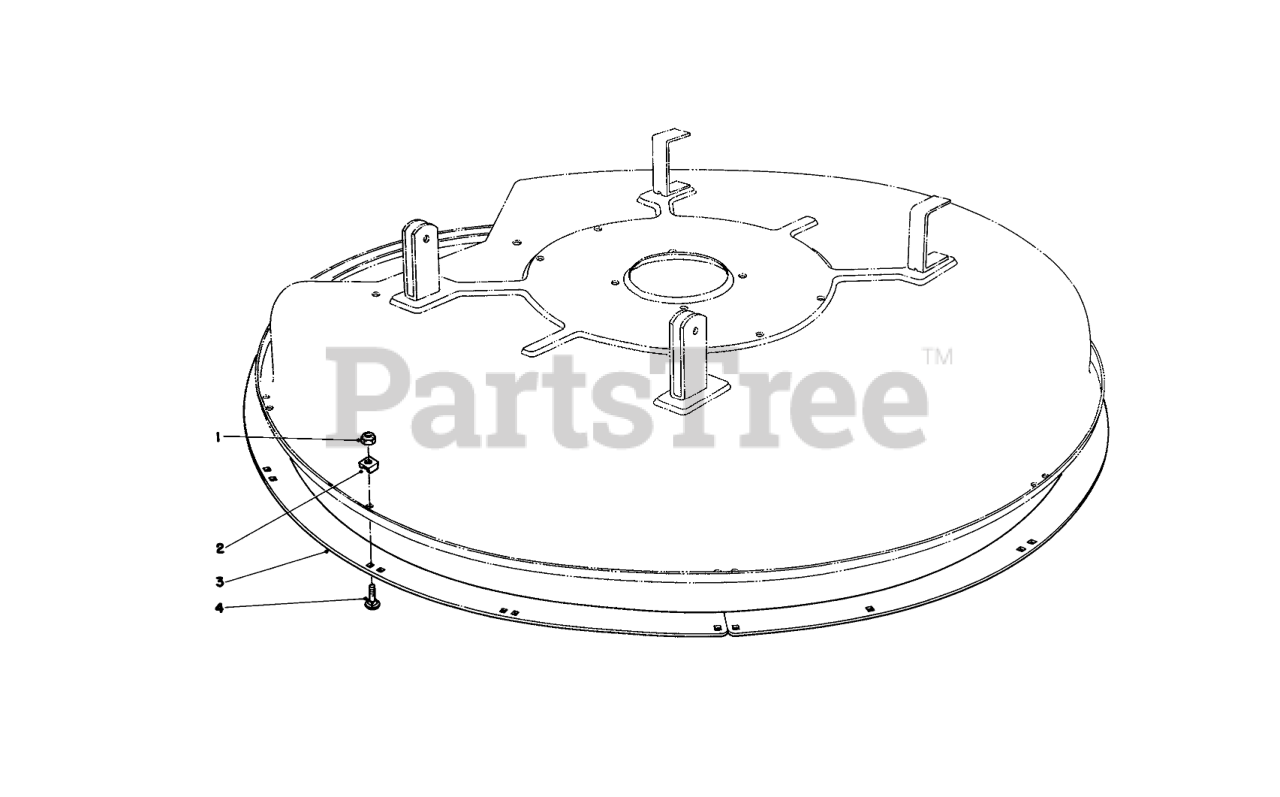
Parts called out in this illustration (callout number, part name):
1	NUT-LOCK, NI
2	DECK RING SPACER
3	DECK RING B
4	BOLT-CARR
